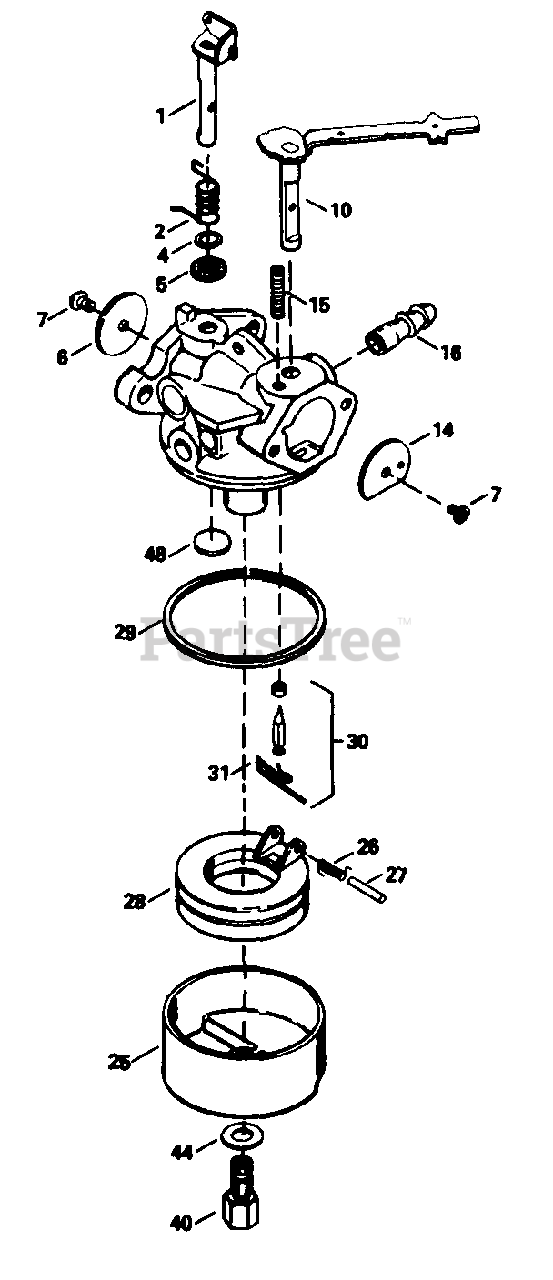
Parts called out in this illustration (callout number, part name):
1	Throttle Shaft & Lever Ass'y.
2	Throttle Return Spring
4	Dust Seal Washer
6	Throttle Shutter
7	Throttle and Choke Shutter Screw
10	Choke Shaft and Lever Ass'y.
15	Choke Positioning Spring
16	Fuel Fitting
25	Float Bowl
26	Float Dampening Spring
27	Float Shaft
28	Float
29	O-Ring, Float Bowl to Body
30	Inlet Needle, Seat & Clip
31	Spring Clip
40	High Speed Bowl Nut
44	Bowl Nut Washer
48	Welch Plug, Atmospheric Vent
